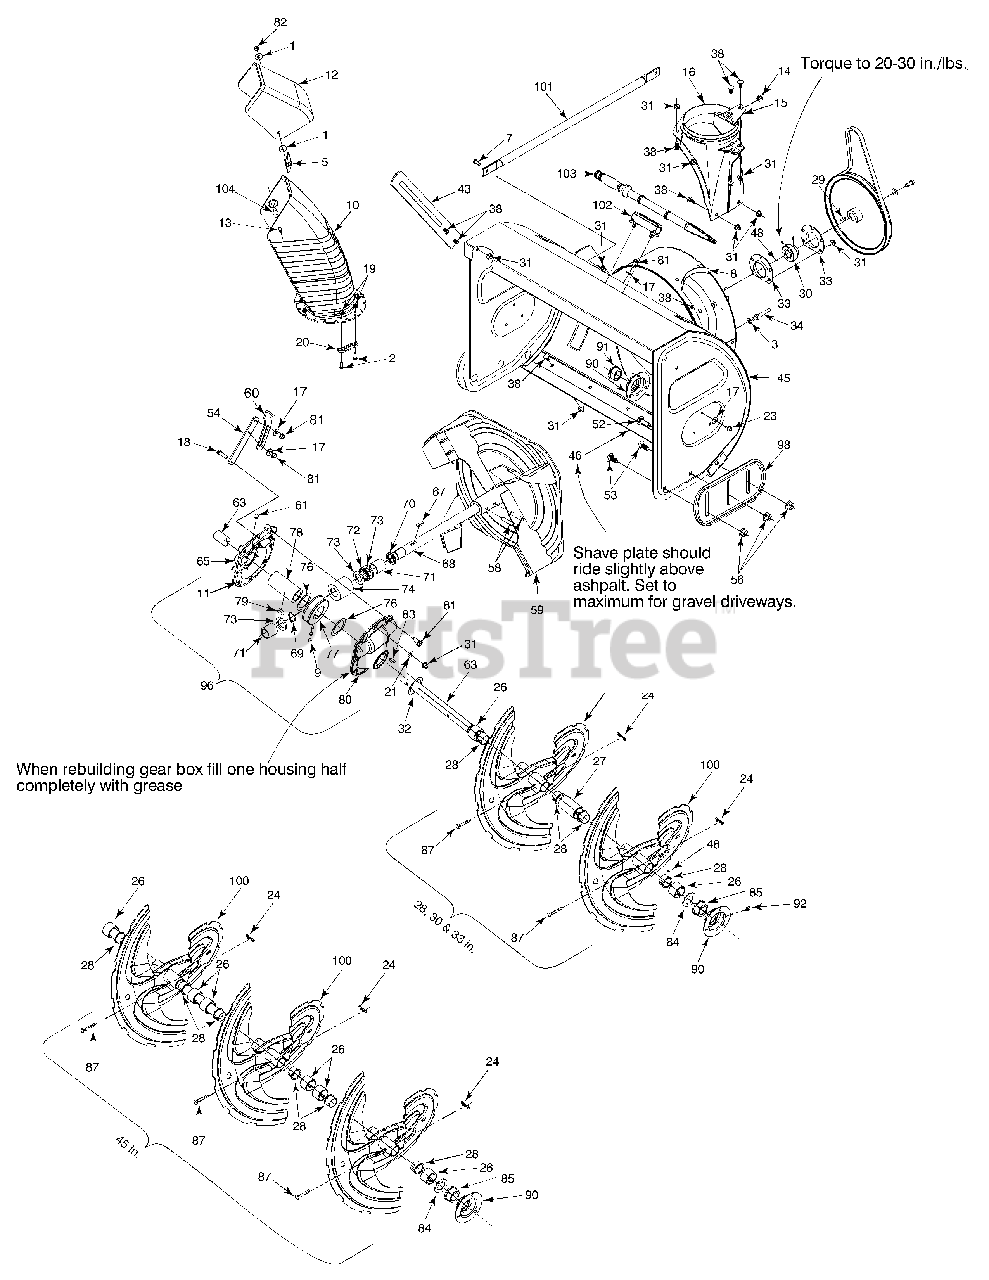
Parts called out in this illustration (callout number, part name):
1	Flat Washer .344 ID x .875 OD
2	Hex. Scr. 1/4-20 x 1.00 Gr. 5
3	Lockwasher 3/8" ID
5	Handle Knob Assembly
7	Hex Hd Cap Scr. 5/16-18 x .75 Gr. 5
10	Extended Lower Black Plastic Chute
11	Ultra Grey Loctite #5699 (purchase locally)
12	Upper Black Plastic Chute
13	Carriage Bolt 5/16-18 x 1.00" Lg
14	Plastic Bushing .380 ID
16	Chute Adapter
17	Cupped Washer .345 ID x .88 OD x .06
18	Hex Screw 5/16-18 x 1.25
19	Hex Flange L-Nut 1/4-20 Gr. F Nylon
20	Chute Flange Keeper
21	Lockwasher 5/16" ID
22	Flange L-Nut 5/16-18 Gr. 5 Nylon
23	Hex Wash HD Tap Scr 5/16-18 x .75
24	Bow Tie Cotter Pin
26	Spacer 1.5 x 1.0 ID x 1.0" Lg.
27	Spacer 1.5 x 1.0 ID x 2.5" Lg.
28	Flange Bushing 1.05 ID x 1.16 OD
29	#9 HI-Pro Key 3/16 x 3/4 Dia HT
30	Self-Aligning Bearing .875 ID
31	Hex Flg. L-Nut 5/16-18 Gr. F Nylon
32	Flat Washer 1.010 x 1.88 x .060
33	Bearing Housing
34	Belt Keeper Studs 3/8-16 x 2.75
38	Carriage Bolt 5/16-18 x .75
48	Arctic Grease
52	Carriage Bolt 3/8-16 x 1.00 Gr. 5
53	Carriage Bolt 3/8-16 x .75" Lg.
56	Hex Flange L-Nut 3/8-16 Gr. F Nylon
58	Spring Spirol Pin Heavy - 5/16 dia x 1.7
63	Spiral Axle 28"
63	Spiral Axle 33"
63	Spiral Axle 45"
65	Gear Housing Half - RH
67	#9 HI-Pro Key 3/16 x 3/4 Dia HT
68	Auger Drive Shaft
69	Snap Ring for .875 dia. shaft
70	Oil seal for .875 ID Garlock (76 x 6133)
71	Sleeve Bearing .875 ID
72	Thrust Bearing .88 ID x 1.44 OD x .078
73	Flat Washer .88 ID x 1.4 OD x .125
74	Worm Gear LH Double Thread
76	Flat Washer 1.5 ID x 2.0 OD x .03
77	Worm Gear LH Double Thread (Bronze)
78	Worm Gear Shaft
79	#91 Woodruff Key 1/4 x 3/4 Dia.
80	Gear Housing Half LH
80	Gear Housing Half LH (w/grease fitting hole)
81	Hex Flange Scr. 5/16-18 x .75
82	Hex Ins. L-Nut 5/16-18
83	#91 Woodruff Key 1/4 x 3/4 Dia.
84	Spacer
85	Flange Bearing
87	Shear Bolt 5/16-18 x 1.75
91	Flange bearing w/flats
92	Grease Fitting (optional)
96	Worm Gear Box Ass’y
96	Worm Gear Box Ass’y (w/grease fitting)
